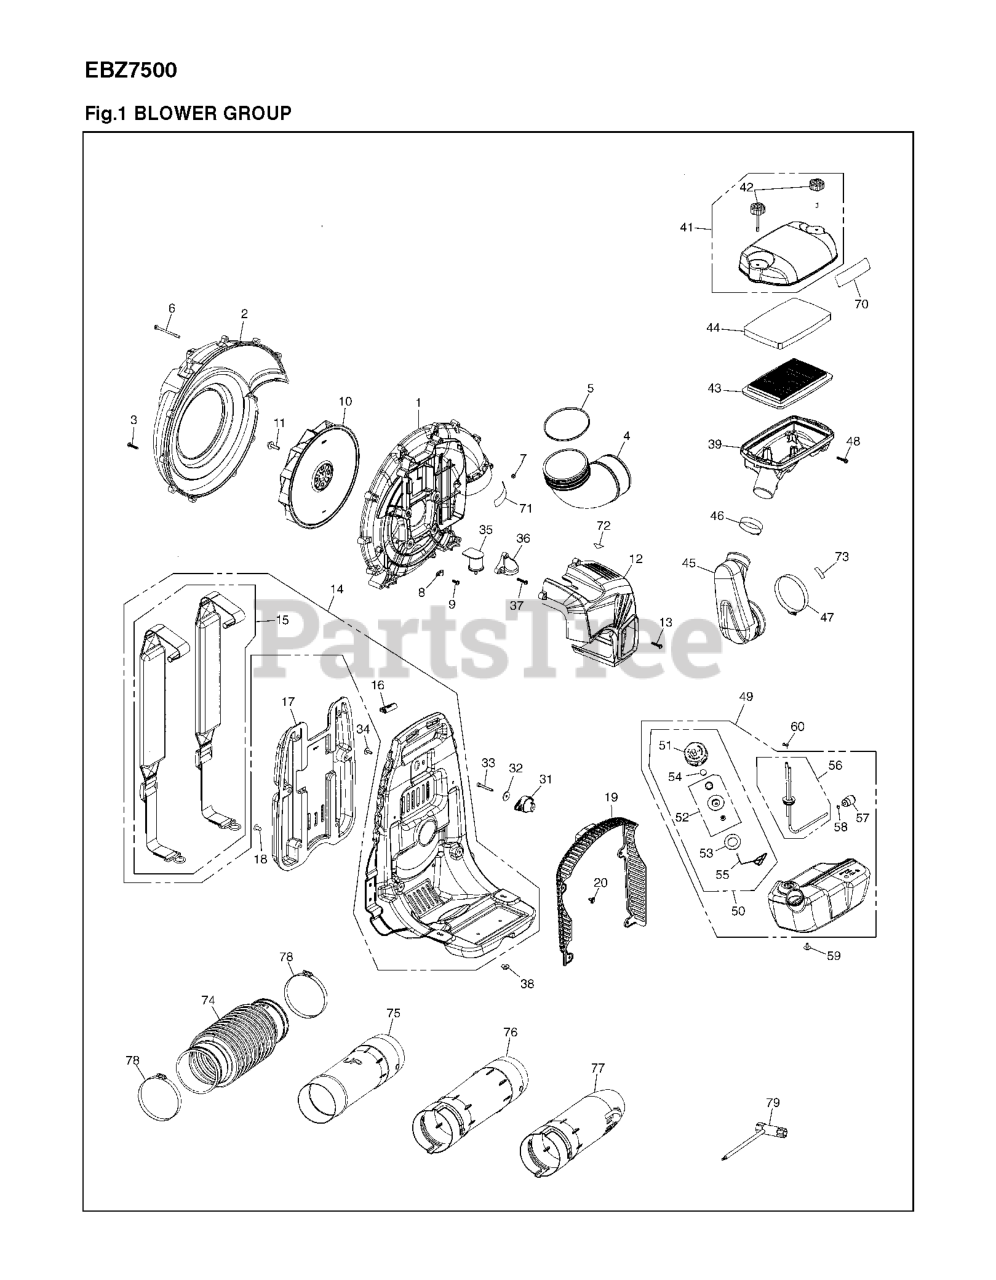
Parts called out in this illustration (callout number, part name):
2	VOLUTE,COVER
5	0-RING
8	CLAMP
10	FAN
12	ENGINE COVER
14	FRAME ASSY
15	BAND ASSY (RPLS 848L583611)
16	CLIP
18	CLIP
19	NET
20	CLIP
31	DAMPER UPPER
33	BOLT
39	BODY AIR FILTER
41	COVER
42	KNOB BOLT
43	ELEMENT
44	ELEMENT
46	CLAMP(F64)
47	CLAMP(F96)
49	TANK ASSY
50	ASSY FUEL CAP
52	HOLDER-A
56	PIPE
57	FILTER ASSY
58	CLIP
60	CLIP
70	DECAL,CLEANER
71	DECAL
73	LABEL,CHOKE
74	HOSE
76	PIPE
77	PIPE
78	CLAMP(F115)
79	SOCKET
